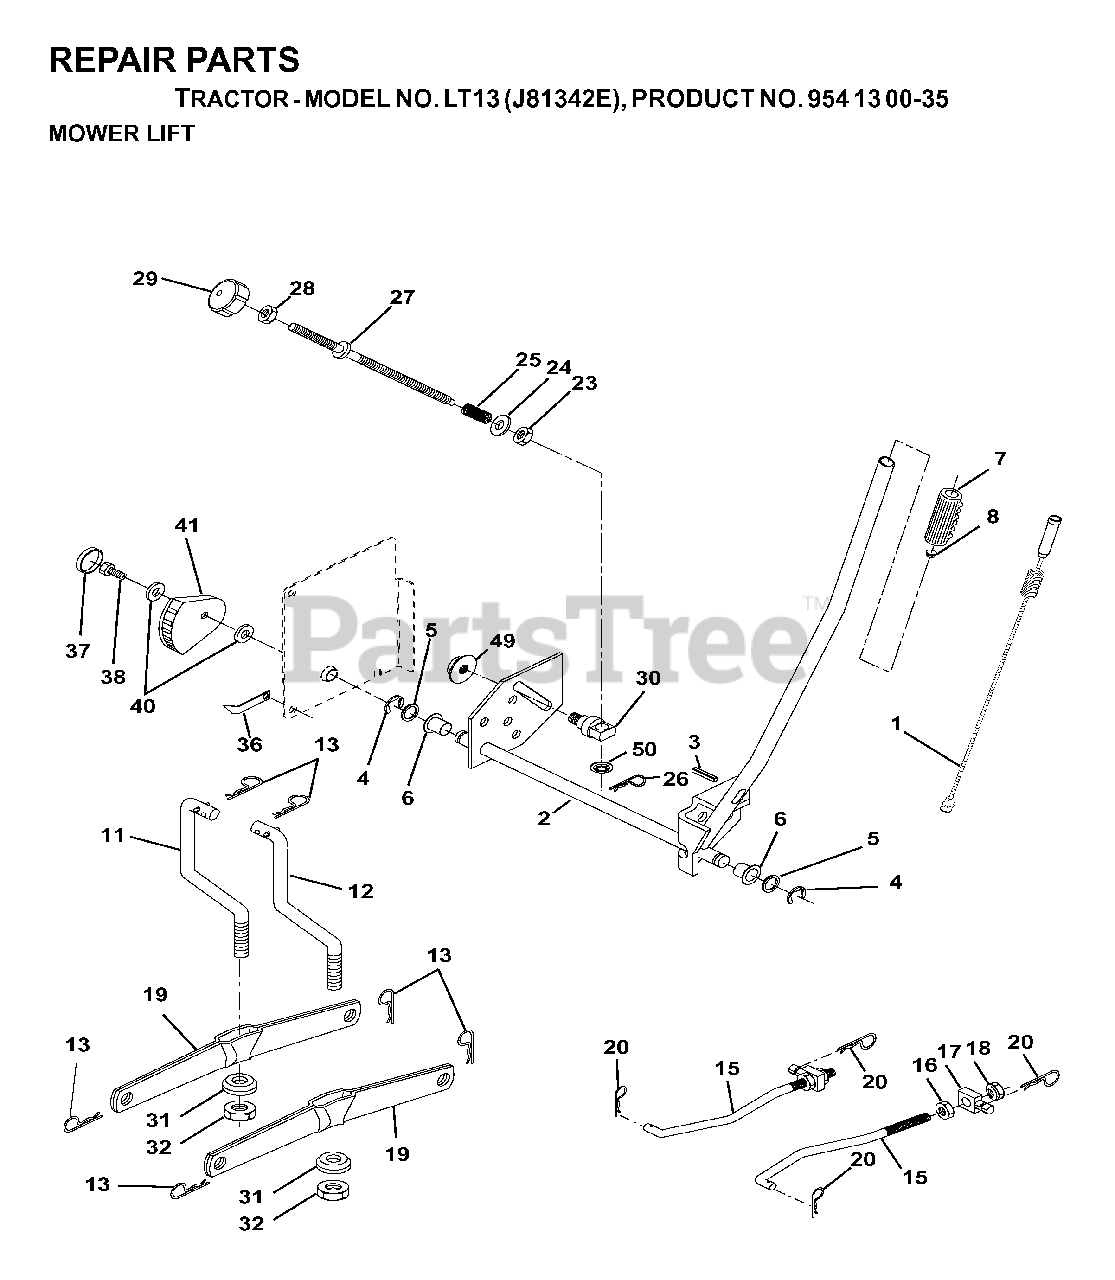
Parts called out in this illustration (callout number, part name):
1	WIRE ASM INNER W/ PLUNGER LT
2	SHAFT ASM R HANDLE
3	PIN GROOVE
4	RETAINING RING LT
6	BEARING.NYLON
7	GRIP HANDLE
11	LINK LIFT LH
12	LINK LIFT RH
13	RETAINER-SPRNG RB
15	LINK FRONT
16	NUT
17	TRUNION
18	NUT
19	ARM.REAR.SUSPENSION
20	SPRING RETAINER
25	SPRING**
26	RETAINER CLIP
27	ROD ADJ LIFT
28	NUT
29	KNOB INF 3/8-16
31	BEARING PIVOT
32	NUT CROWNLOCK 3/8-24
36	POINTER, HEIGHT INDICATOR
37	PLUG,HOLE
38	SCREW 5/16-18X1
41	IND. HEIGHT STLT
49	NUT
50	NUT PUSH M
51	RETAINER-SPRNG RB
